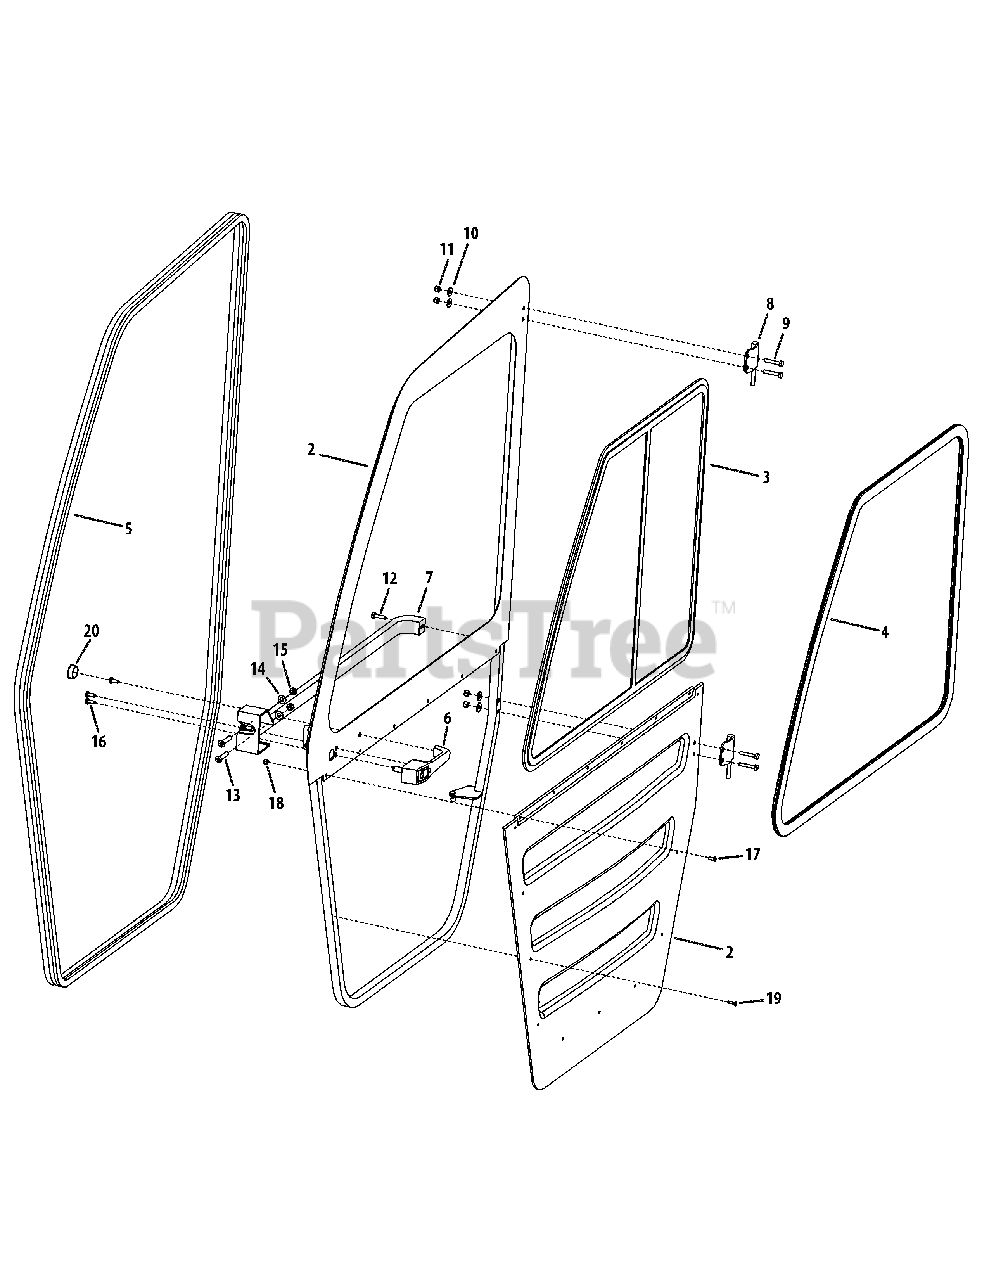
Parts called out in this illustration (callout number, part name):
2	Door Frame with lower Panel, LH
3	Sliding Window, Temp. Glass
4	Window Mounting Rubber - 10'
5	1-1/2" Side Bulb & 2 Wipers - 15'
6	Outside Handle (Set Of 2)
7	Door Latch LH - Non Locking
8	Tube Frame Hinge, LH
